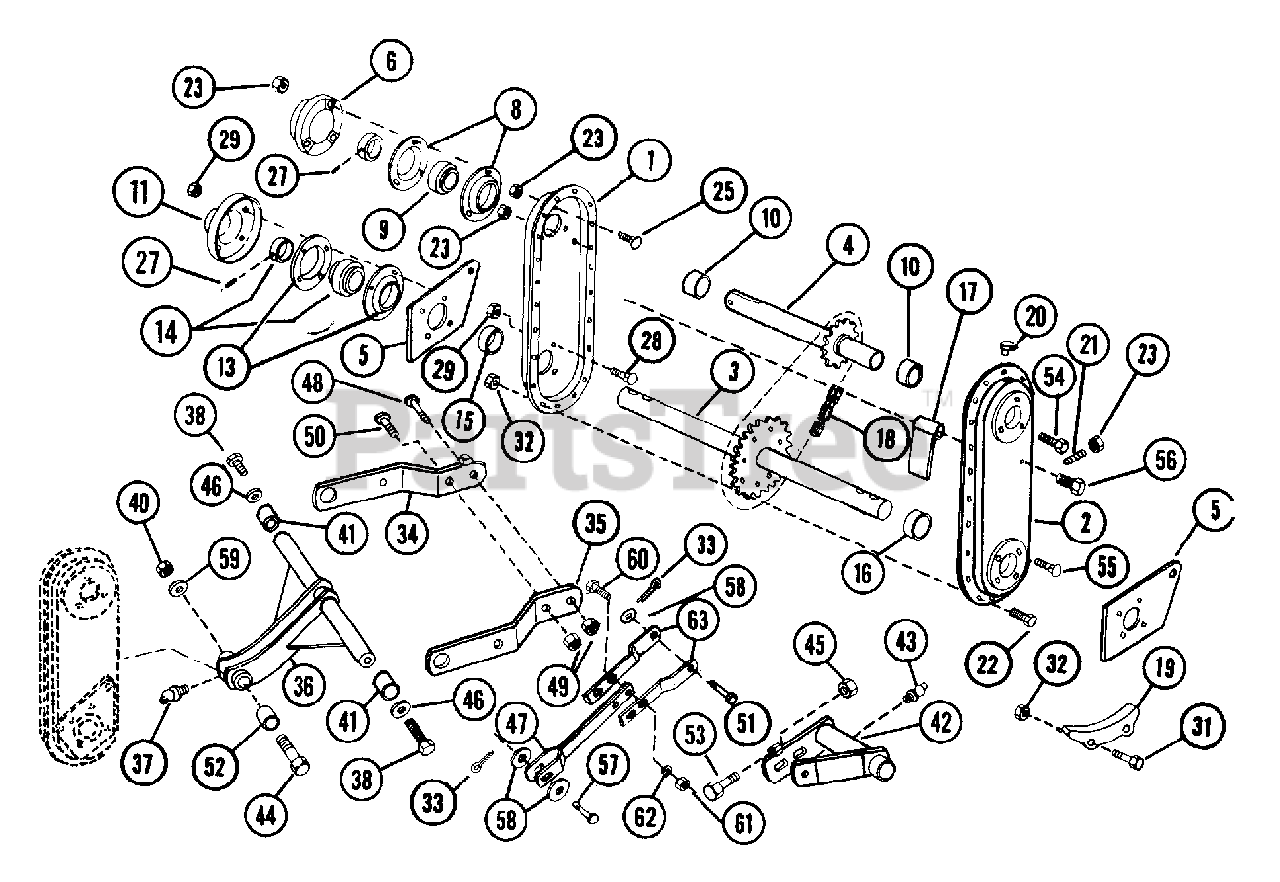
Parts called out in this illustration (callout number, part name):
1	L H CHAIN HOUSING
2	R H CHAIN HOUSING
3	TINE SHAFT & SPROCKET
4	SHAFT & SPROCKET
5	R H LOWER LINK PLATE
6	PIVOT HUB
8	MTG-FLG 3 HOLE 47MMX3.56
9	BRG-BALL 1.00X1.85X.69
10	SPACER 1.050X1.312X.410
13	MTG-FLG 4 HOLE 62MMX4.40
14	BRG-BALL 1.25X62MMX1.906
14	BEARING COLLAR
15	SPACER 1.380X1.660X.435
16	SPACER 1.380X1.660X.310
17	CHAIN TIGHTNER
19	WEAR BAR
20	OIL HOLE COVER
21	SCR-SET .32-18X.50 SKH
22	BLT-HEX .25-20X.50 PL GR5
23	NUT-LK .312-18 GR A PL
25	BLT-RDHDSQNK .31-18X1.50 GR5PL
27	SCR-SET .32-18X.25 SKHCUP OH
28	BLT-RDHDSQNK .38-16X1.50 GR5PL
29	NUT-LK-CTR .375-16 GR A PL
31	BLT-HEX .25-20X2.00 GR5
32	NUT-LK TOP .250-20 PL
33	PIN-HAIR INT .09X.188 PL
34	UPPER ARM LINK
35	UPPER ARM LINK EXTENSION
36	LOWER LINK
37	ZERK FITTING
38	BLT-HEX .50-13X1.25 PL GR5
40	NUT .50-13 PL
41	SPACER .510X.745X.440
42	UPPER LINK
43	SPIN DRIVE ZERK FITTING
44	BLT-HEX .50-13X3.50 PL GR5
45	NUT-JAM .50-13 PL
46	WSHR-FL-STL .781X1.250X.075
47	LIFT LINK
48	BLT-HEX .62-18X3.50 GR5
49	NUT-JAM .625-11
50	BLT-HEX .62-18X2.00 GR5
51	PIN-CLEV .494X1.25 YWZC
52	SPACER .510X.752X2.012
53	BLT-HEX .50-13X2.50 PL GR2 FTH
54	BLT-HEX .25-20X1.00 PL GR5
55	BLT-RDHDSQNK .25-20X.75
56	BLT-HEX .31-18X2.00 PL GR5
57	CLEVIS PIN
58	WSHR-FL-STL.406X.812X.065PL
59	WSHR-FL-STL .531X1.062X.095 PL
60	BLT-HEX .38-16X1.25 PL GR 2
61	NUT-HEX .375-16
62	WSHR-LK .375X.115 HVY PL
